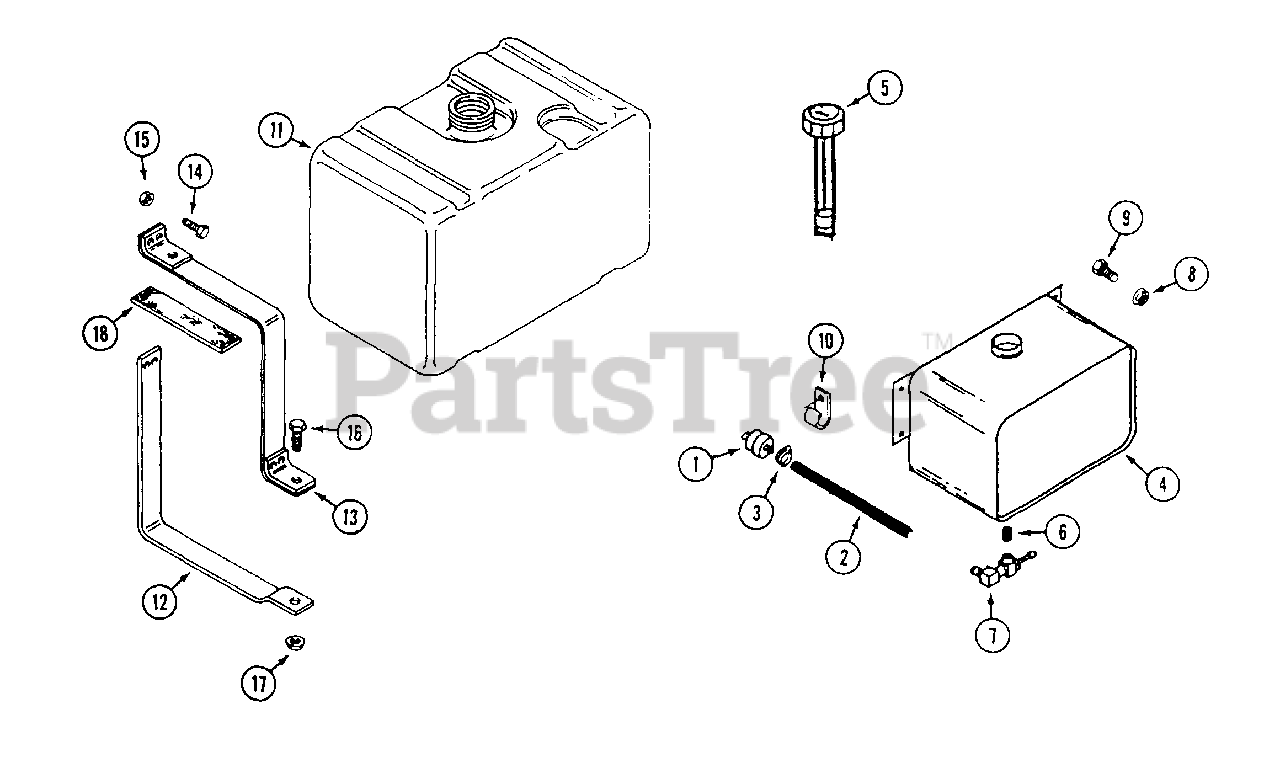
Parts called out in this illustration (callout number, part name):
1	FILTER - fuel
2	HOSE - fuel
4	TANK - fuel (1-3/4" filler tube)
5	CAP - fuel tank (with gauge) (1-3/4" threads)
6	NIPPLE - pipe 1/8"
7	VALVE - shut off
8	NUT - 1/4" - 20 flange lock
9	BOLT - 1/4" - 20 x 1/2"
9	BOLT - 1/4" - 20 x 3/4"
10	CLIP - "J" fuel line
11	TANK - fuel (2-1/4" filler tube) (plastic)
12	BRACKET - fuel tank
13	STRAP - fuel tank
14	BOLT - 1/4" - 20 x l-1/2"
15	NUT - 1/4" - 20 lock
16	BOLT - 5/16" - 18 x 1"
17	NUT - 5/16" - 18 flange lock
